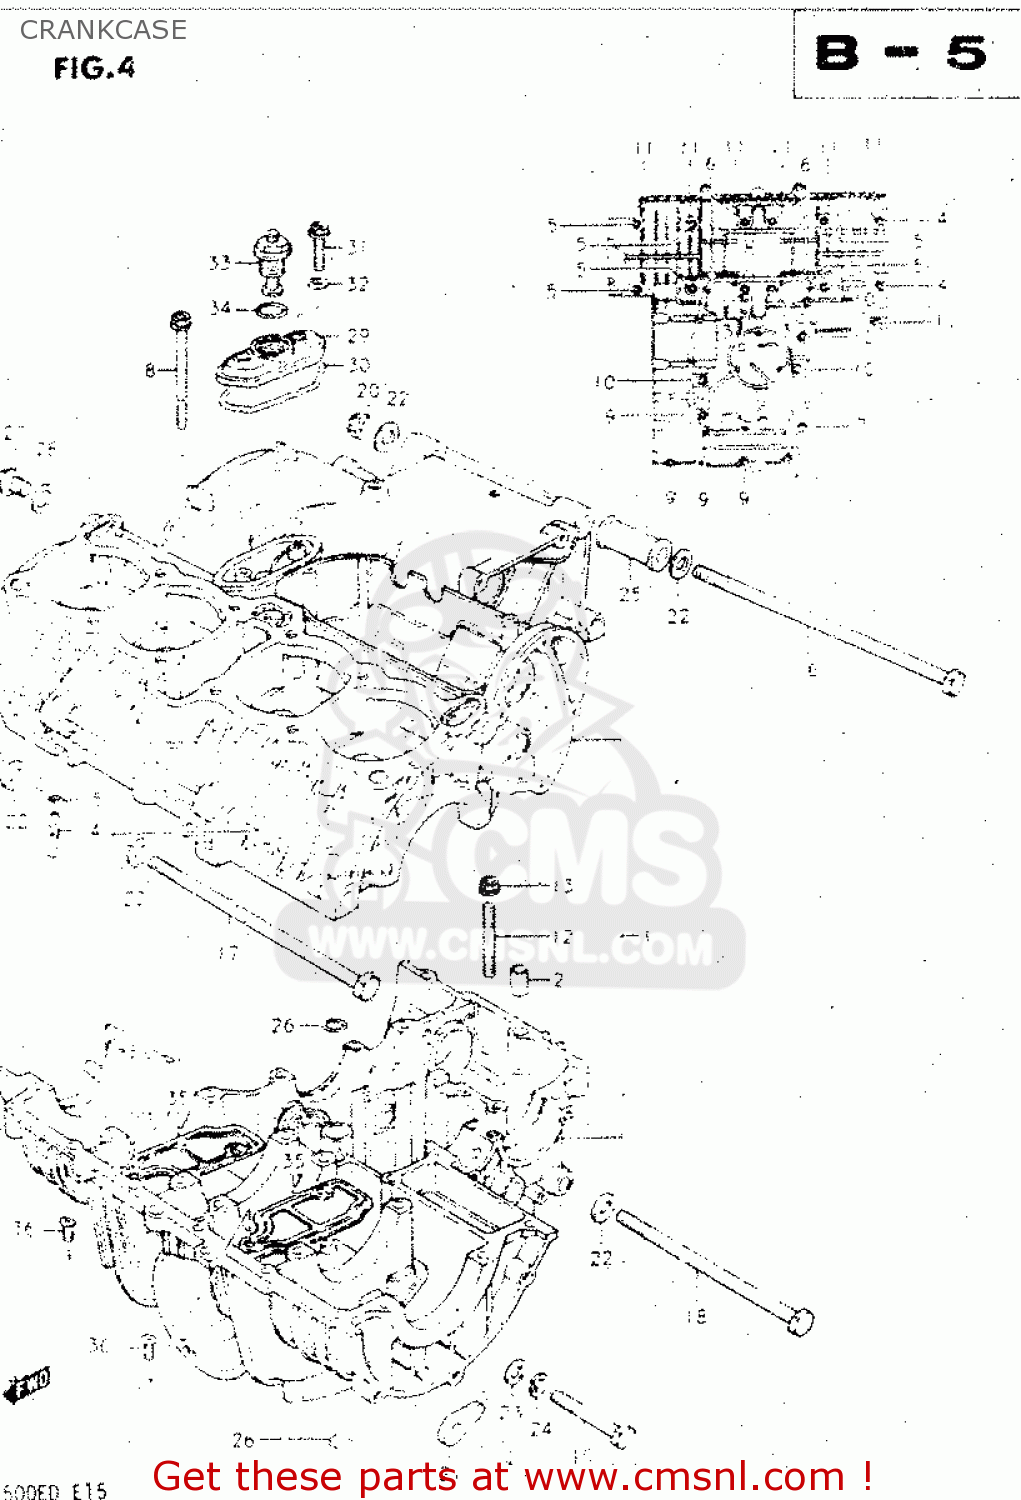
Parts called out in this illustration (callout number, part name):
1	CRANKCASE SET
2	PIN
3	BOLT(8X120)
4	BOLT 8X90
5	BOLT (8X70)
6	BOLT 8X55
7	BOLT (8X45)
8	BOLT (6X90)
9	BOLT (6X60)
10	BOLT ,6X50
11	BOLT
12	STUD BOLT
13	NUT
14	UNION
15	O RING(D:1.05,ID:3.1)
16	BOLT
17	BOLT
18	BOLT
19	BOLT 10X55
20	NUT (10MM)
21	NUT
22	WASHER
23	WASHER (10.5X20X3.2)
24	LOCK WASHER
25	SPACER,ENGINE MOUNT
26	O RING(D:3.2,ID:12.9)
27	PLUG (14X12)
28	GASKET(14X19.2X2) (NAS)
29	HOUSING,OIL PRESSURE SWITCH
30	O RING,PRESSURE SWITCH HOUSING
31	BOLT
32	WASHER
33	SWITCH ASSEMBLY
34	O RING(D:1.9,ID:18.8)
35	PLATE,OIL SEPARATOR
36	SCREW
